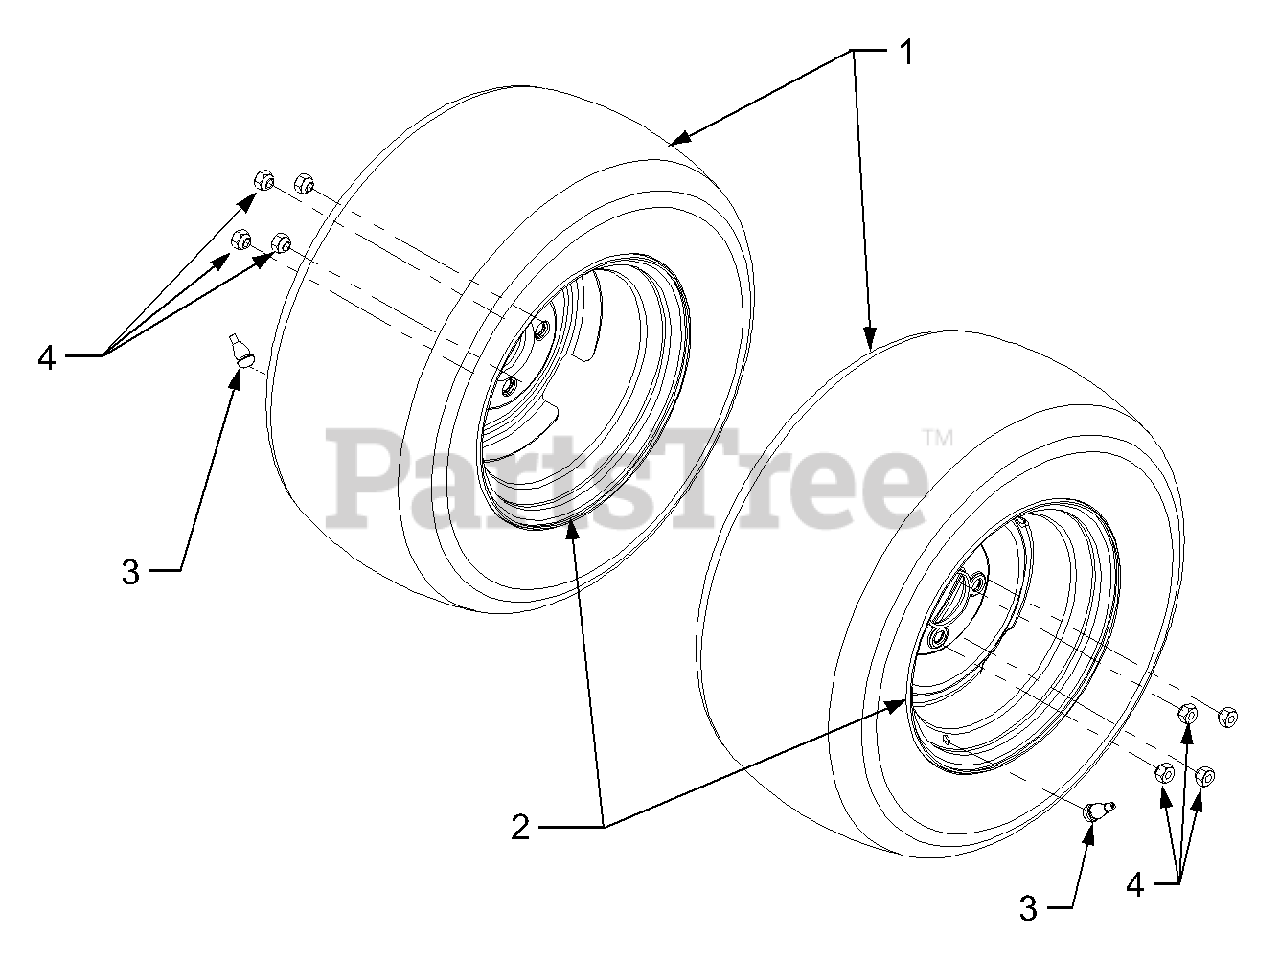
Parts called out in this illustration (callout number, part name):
1	Tire, Turf, 23 x 9.5 - 12
2	Rim Assembly, Wheel
3	Valve, Tubeless Air
4	Lug Nut, 7/16-14
